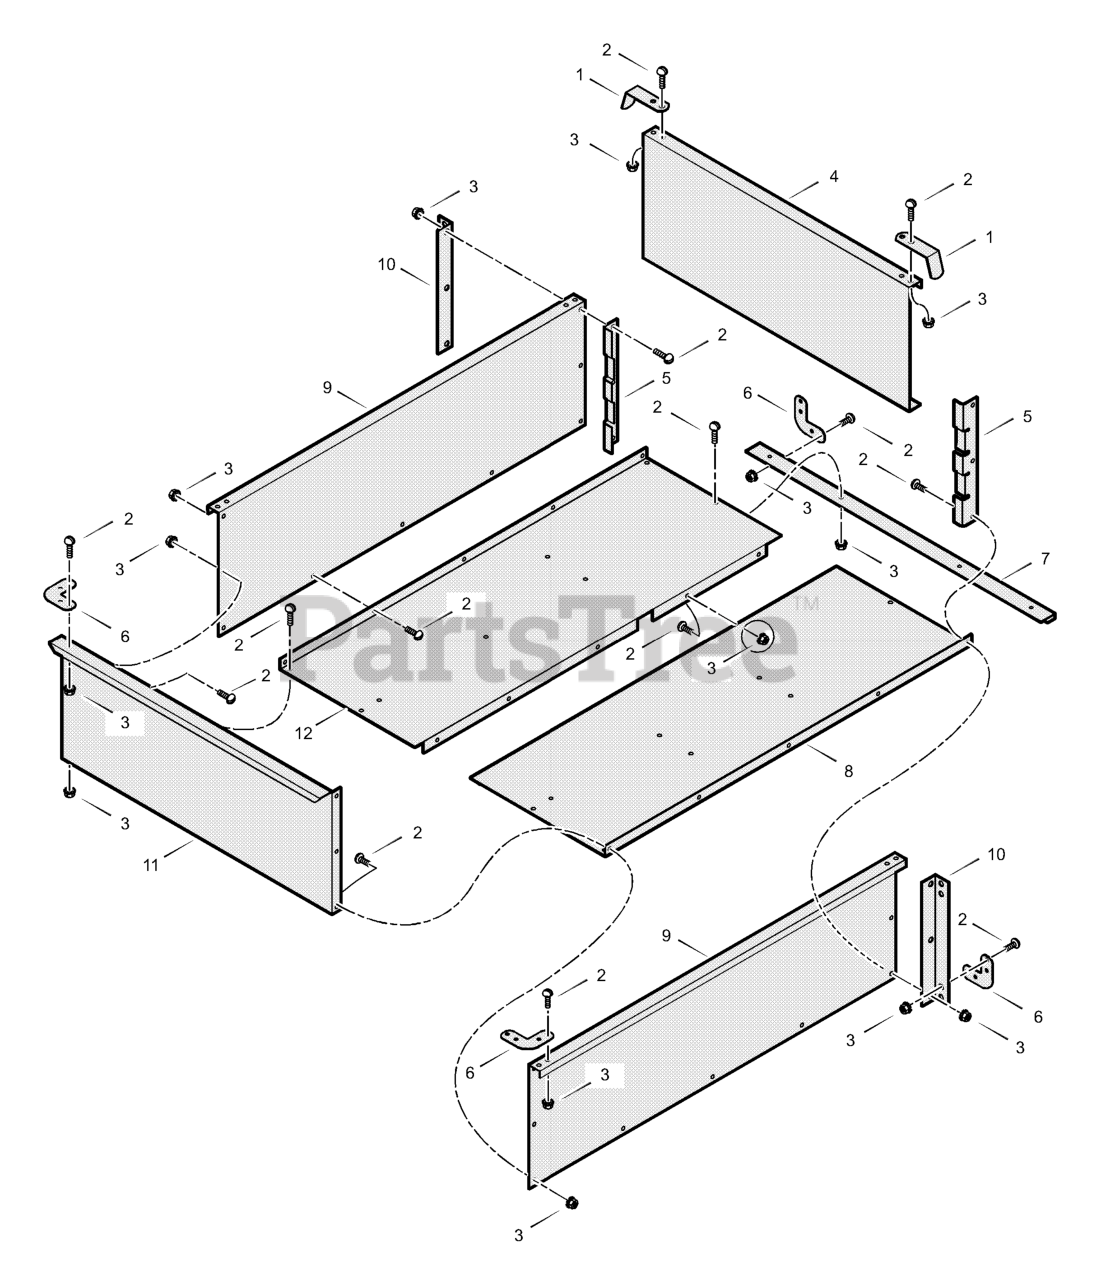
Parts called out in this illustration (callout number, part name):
1	Support, Side
2	Screw 1/4-20x0.50
3	Nut, Keps 1/4-20
4	Tailgate (Black)
5	Retainer, Tailgate
6	Bracket, Corner
7	Brace, Rear
8	Bottom, Right
9	Panel, Side (Black)
10	Support, Side
11	Panel, Front
12	Bottom, Left
